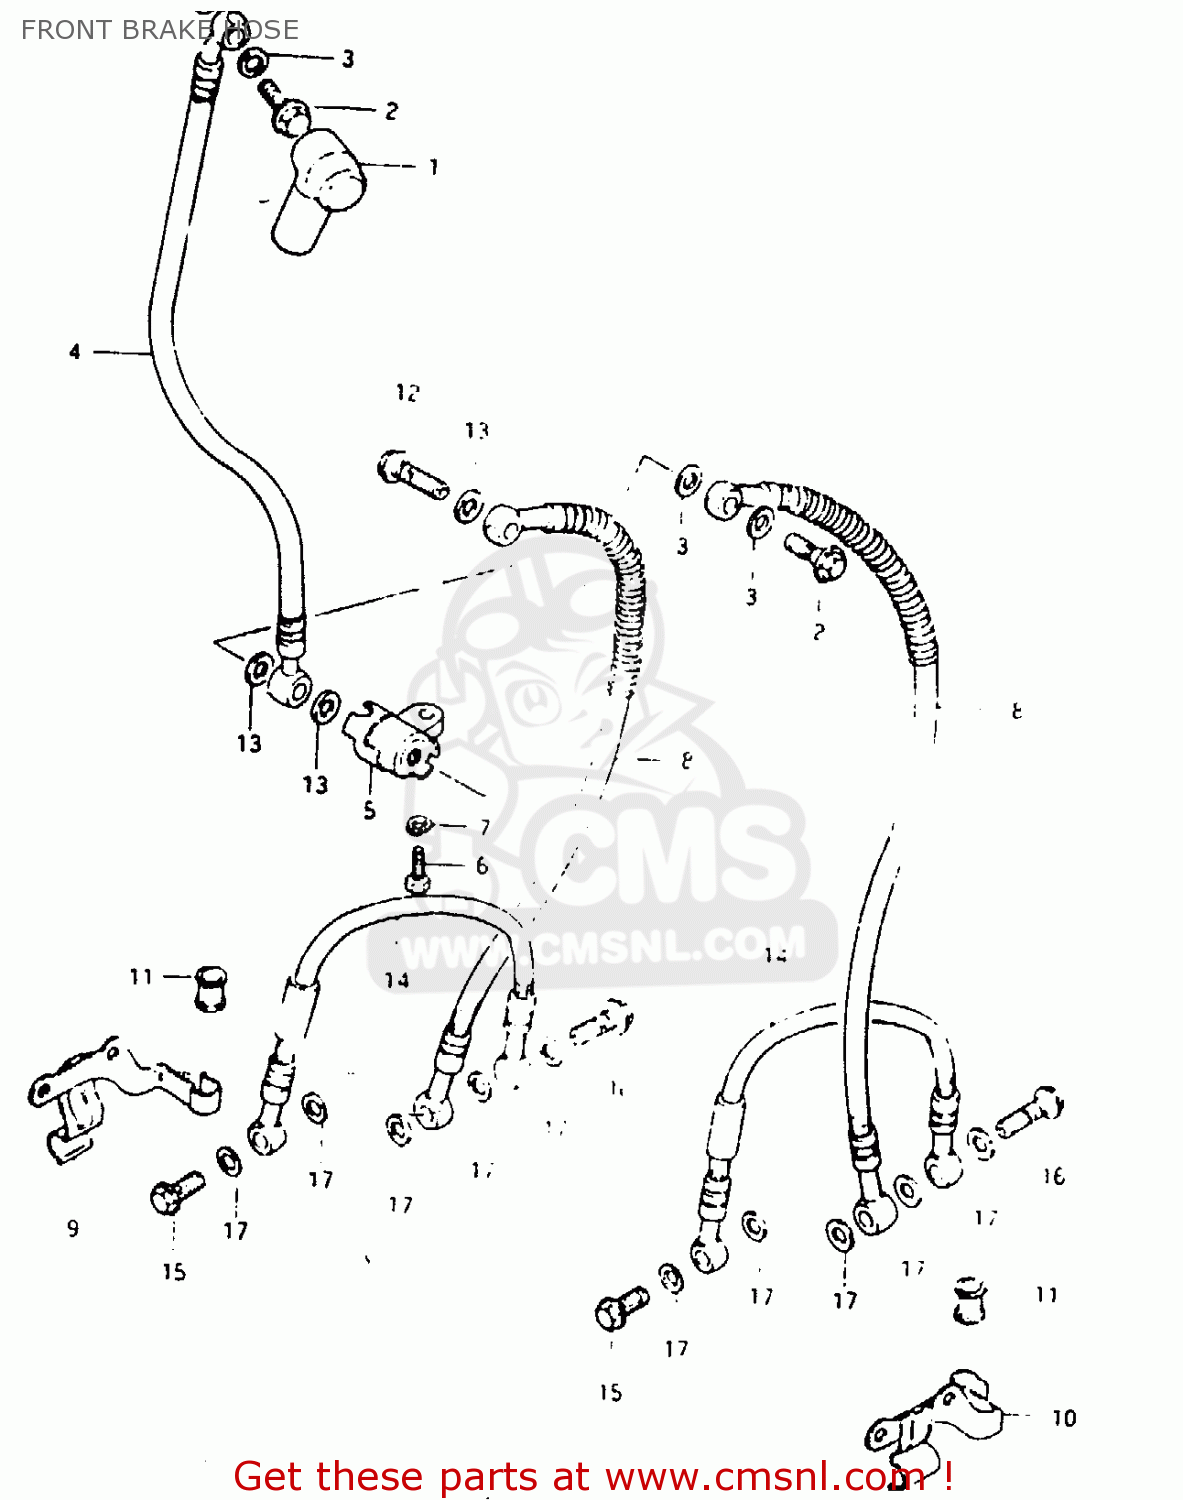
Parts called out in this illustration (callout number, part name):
1	BOOT
2	BOLT,UNION
3	WASHER
4	HOSE, BRAKE NO. 1
5	JOINT,BRAKE HOSE
6	BOLT
7	LOCK WASHER
8	HOSE,FRONT BRAKE
9	CLAMP, HOSE RH
10	CLAMP, HOSE LH
11	BUSH,BRAKE HOSE GUIDE,NO.2
12	BOLT,UNION
13	WASHER
14	HOSE, ANTI NOSE
15	BOLT,UNION
16	BOLT,UNION
17	WASHER
